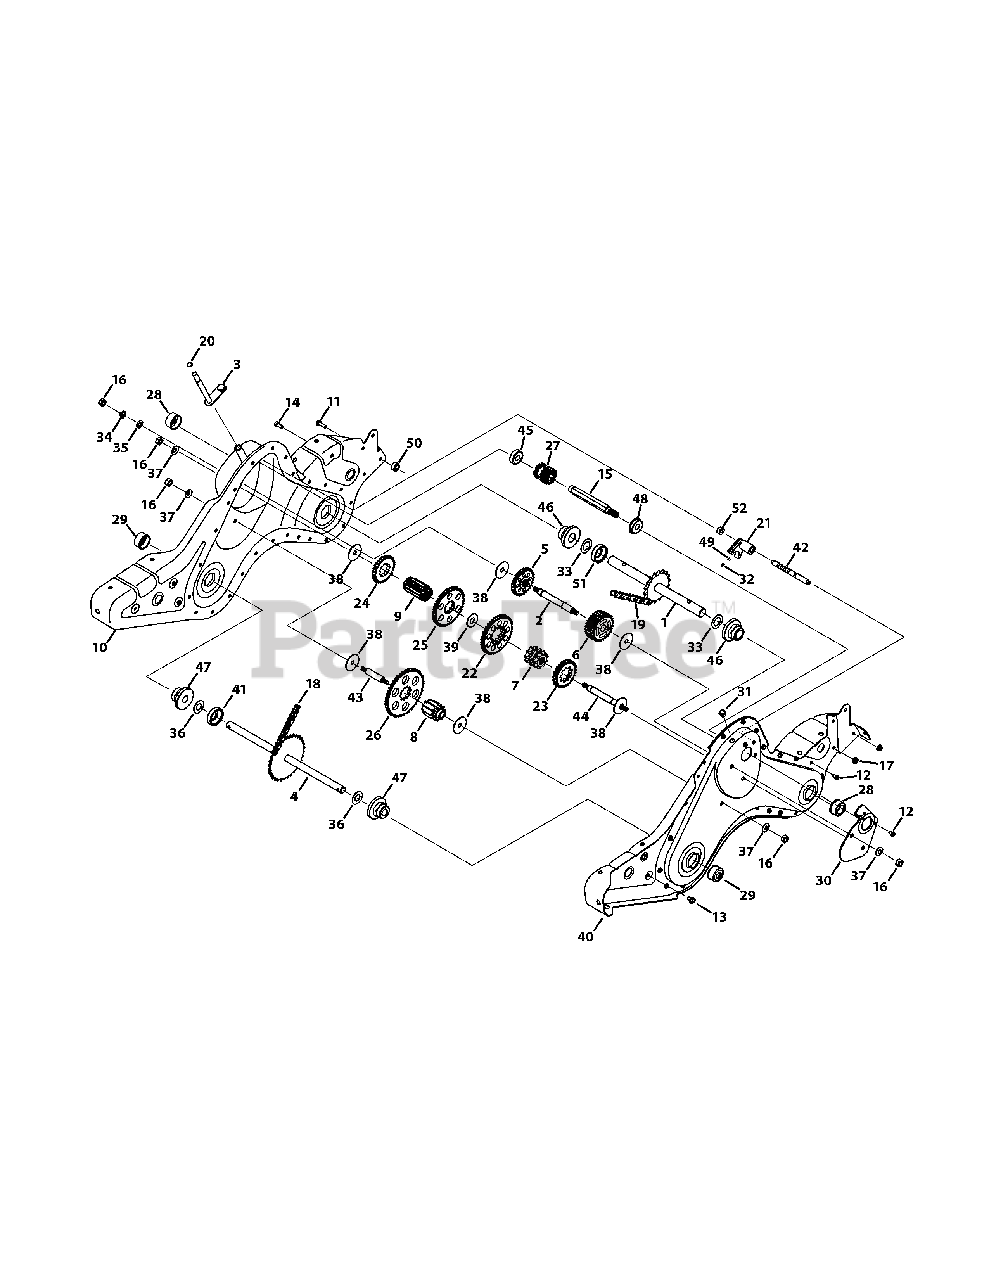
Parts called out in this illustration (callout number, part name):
1	Shaft Assembly, Tine, 18T
2	Shaft Assembly, Jack
3	Shaft Assembly, Shift Input
4	Shaft Assembly, Wheel, 33T
5	Gear Assembly, 30T Reverse Idler
6	Gear Assembly, 30T Tine Idler
7	Sprocket Assembly, 9T Tine Input
8	Sprocket Assembly, 10T Whl Input
9	Gear Assembly, 11T
10	RH Chain Case Housing Assembly
11	Hex Head Screw, 5/16-18 x 1.00
12	Screw, 1/4-20 x 0.500
13	Screw, :5/16-18 x 0.625
14	Hex Head Screw, 5/16-18 x .75
15	Input Shaft, .75
16	Nut, Hex, 7/16-20
17	Nut, Flangelock, 5/16-18
18	Endless Chain, #420 x 50 Links
19	Endless Chain, #50 x 54 Links
20	Snap Ring, .500
21	Clutch Collar
22	Gear Spur, 44T
23	Gear Spur, 30T
24	Gear Spur, 30T
25	Gear Spur, 44T
26	Gear Spur, 44T
27	Gear Spur, 16T
28	Shaft Seal, 1.0
29	Shaft Seal, .75
30	Positioner Gear Bracket
31	Tapered Cap Plug
32	Compression Spring, .230 OD
33	Washer, Flat, 1.03 x 1.62 x .03
34	Washer, Lock, 7/16
35	Washer, Flat,.474 x .879 x .064
36	Washer, Flat, .760 ID x 1.50 OD
37	Washer, Bell,.45 x 1.00 x .062
38	Washer, Thrust, .445 x 1.92 x .060
39	Washer, Flat,1.595 x .635 x .062
40	LH Chain Case Housing
41	Spacer, .75 x 2.0 x .50
42	Shaft Detent, .5 DIA
43	Shaft, Jack, .625 x 2.385
44	Shaft, Jack, .6250 x 5.0050
45	Ball Bearing, 17 x 40 x 12:6203
46	Flange Bearing, 1.0 x 2.5 x 1.38
47	Flange Bearing, .75 x 2.5 x 1.38
48	Ball Bearing, 17 x 40 x 12:6203
49	Ball, Detent, .250
50	Spacer, .315 x .750 x .375 LG
51	Spacer, 1.0 ID x 2.0 OD x.5 LG
52	Spacer, .505 ID x .88 OD x .440
